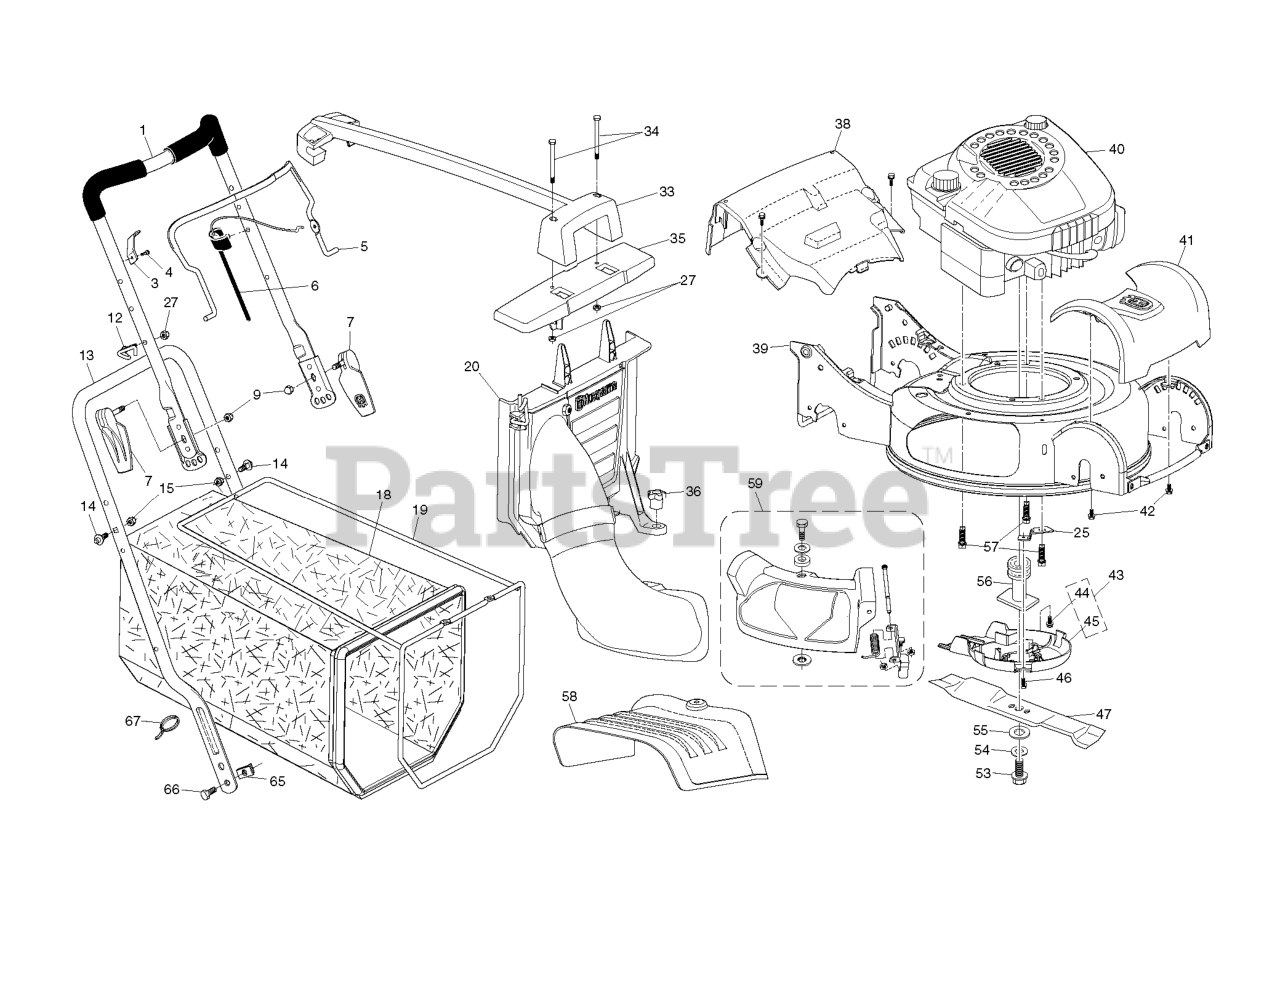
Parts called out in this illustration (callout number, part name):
1	HANDLE.ASM.UP.W/ADJ.BKT
3	BRACKET.UPSTOP.RT
5	BAIL.CONTROL.MZR.BS.ORANGE
6	CABLE.MZR.47.75.SNAP-IN.PU.L
7	QUICK.ASM.RELEASE.BLACK
9	Locknut, Hex 1/4-20
12	RB GUIDE.ROPE.STD.BLK.ZIN WSL
14	STUD.QUICK.ADJUST
15	NUT.LOCK.5/16-18
25	BRACKET
27	NUT
36	KNOB.MULCH.DOOR
42	SCREW.HWH.13-16-5.8.BZP
44	HINGE SCREW
46	SCREW.HEX.WSH
47	BLADE.SWEPT.WING.45CM.H.TREAT
53	BOLT.HD.HEAD.3/8-24X2.50 (2 2)
54	LOCKWASHER
55	WASHER,HARDEN
56	ADAPTER.BLADE
57	BOLT 3/8-16X1-1/8
67	TIE GUIDE
